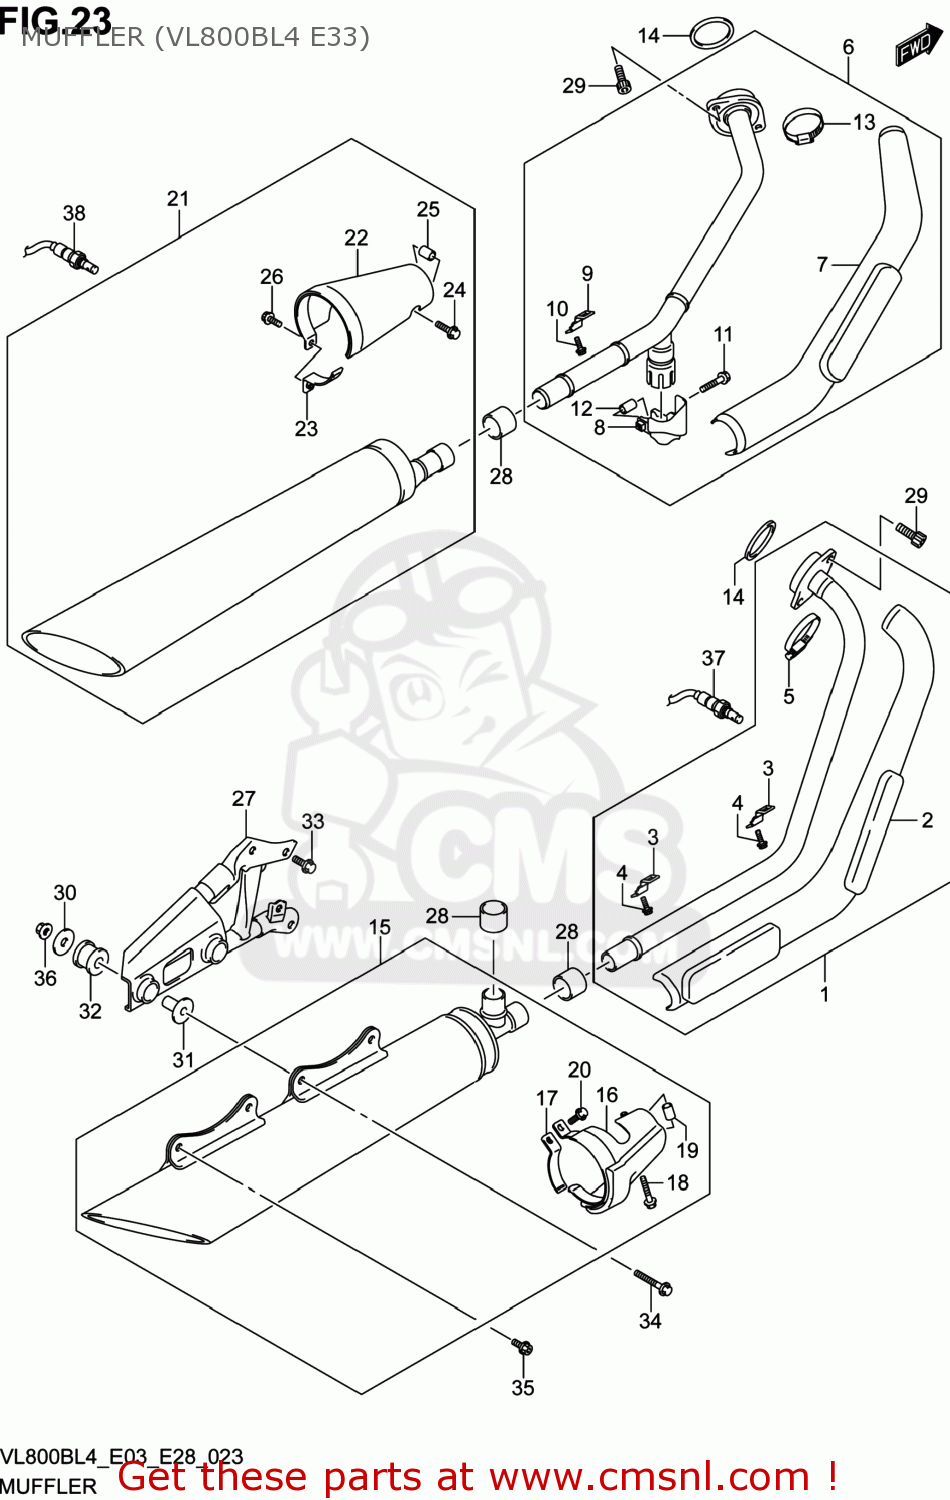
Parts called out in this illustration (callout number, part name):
1	PIPE,EXH FR
2	COVER
3	CLAMP,EXHAUST COVERER
4	BOLT
5	BAND
6	PIPE,EXH RR
7	COVER
8	CLAMP, CONNECTOR
9	CLAMP,EXHAUST COVERER
10	BOLT
11	BOLT(8X35)
12	SPACER
13	BAND
14	GASKET,EXHAUST PIPE (NAS)
15	BODY,MUFFLER FR
16	COVER
17	CLAMP
18	BOLT(8X35)
19	SPACER
20	BOLT
21	BODY,MUFFLER RR
22	COVER
23	CLAMP
24	BOLT(8X35)
25	SPACER
26	BOLT
27	BRACKET,MUFFLER SUPPORT
28	CONNECTOR,MUFFLER
29	BOLT(8X25)
30	WASHER(8.5X33X1.5)
31	SPACER(8.6X12X27.1)
32	CUSHION
33	BOLT(8X16)
34	BOLT
35	BOLT(8X20)
36	NUT
37	SENSOR,OXYGEN
38	SENSOR,OXYGEN
